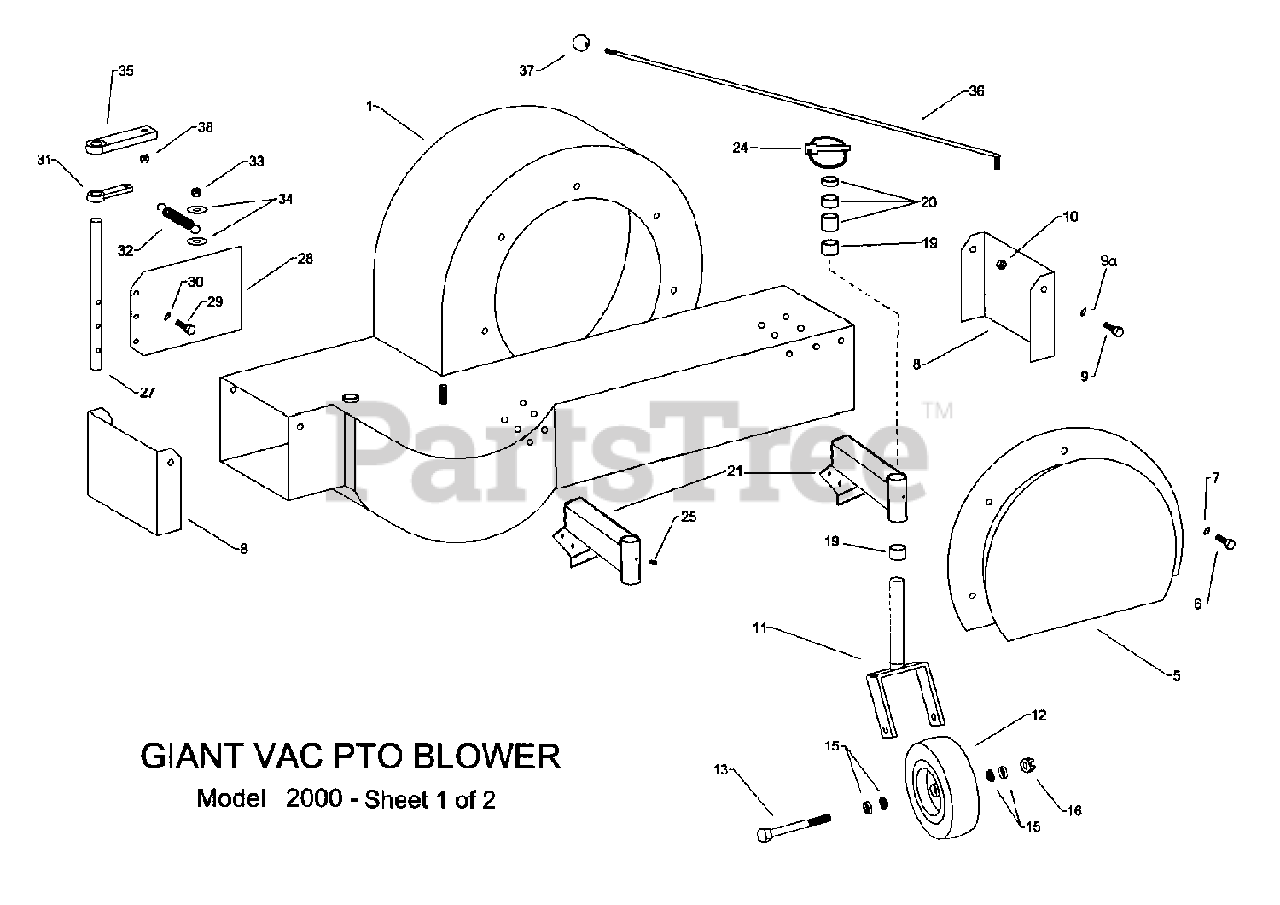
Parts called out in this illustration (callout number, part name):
1	Blower housing & shaft frame
5	Intake baffle
6	5/16 x 3/4 hex bolt
7	5/16 lockwasher
8	Deflector
9	3/8 x 1 hex bolt
10	3/8 lock nut
11	Caster horn
12	Caster wheel - 410-350x4
13	5/8-11 x 5 hex bolt
15	Wheel bearing
16	5/8-11 hex nut
19	Caster horn flange bushing (1 ID)
20	Caster spacer - 1/4
20	Caster spacer - 1/2
21	Caster arm
24	¼ x 2 snapper pin
25	Caster horn grease fitting
27	Inner deflector door rod
28	Inner deflector door
29	5/16 x ¾ hex bolt
30	5/16 lockwasher
31	Spring arm holder
33	3/8 lock nut
34	3/8 flatwasher
35	Deflector rod upper control arm
36	Control rod
37	Control rod knob - 3/8
38	3/8 lock nut
